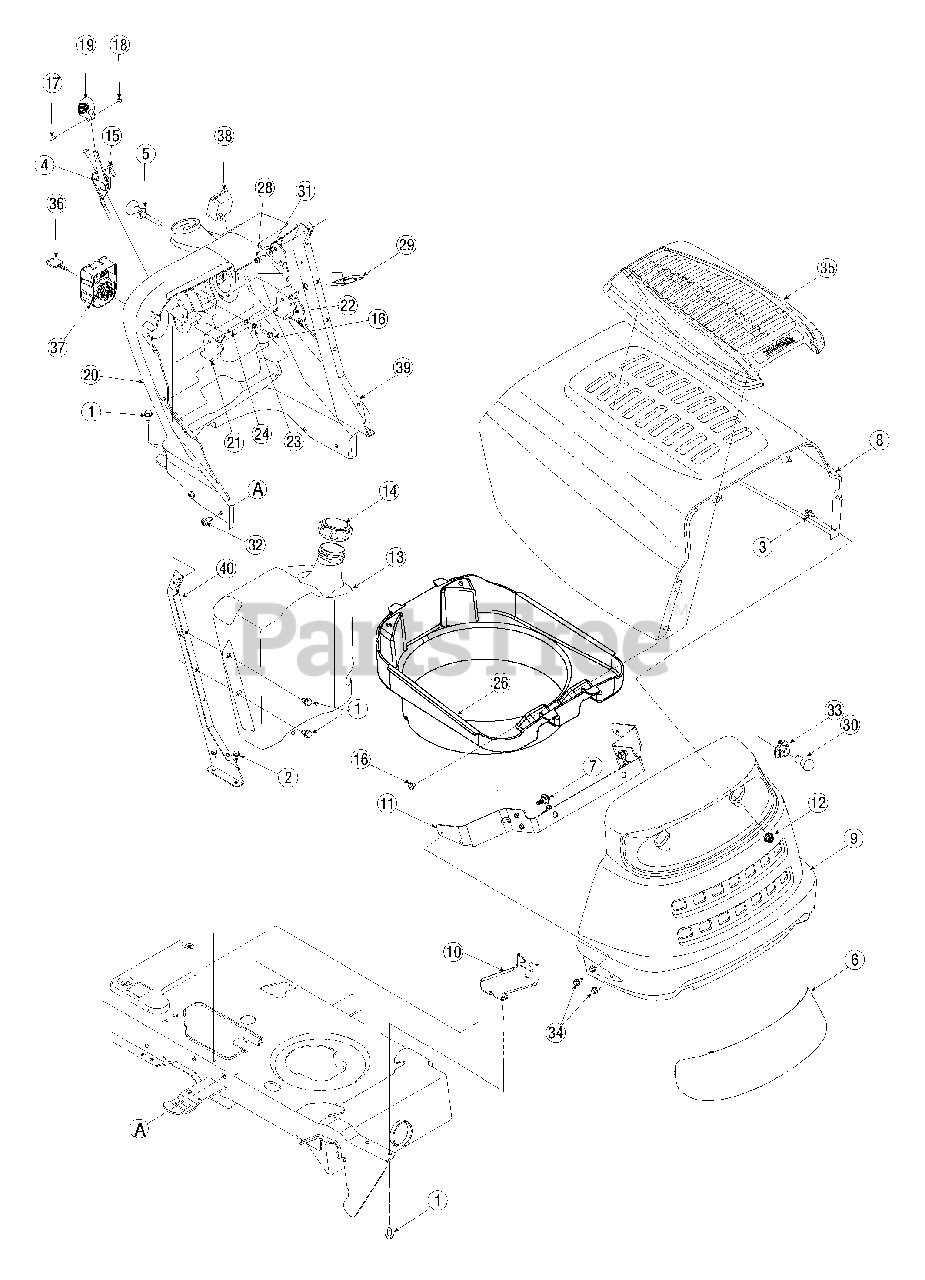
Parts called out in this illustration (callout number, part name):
1	Screw, 5/16-12 x.750
2	Self-tapping Screw, 1/4-20 x.5
3	Hex Cap Screw, 1/4-20 x.62
4	Throttle Cable
5	Choke Knob/Cable
6	Headlight Lens
7	Shoulder Screw,.43 x.29
13	Fuel Tank, Three Gallon
14	Fuel Cap
15	Screw, 1/4-14 x.625
16	Self-tapping Screw, 1/4-15 x.75
17	Truss Phillips Screw, #8-32 x.375
18	Hex Nut, #8-32
19	Throttle Control Knob
20	Dash Panel
21	Cruise Control Button
22	Parking Brake Button
23	Flat Washer, 9/32 x 1/2 x 1/16
24	Brake/Cruise Pivot Rod
26	Hood Plenum
28	Self-tapping Screw, 1/4-20 x.75
29	Switch Brkt., Electric PTO
30	Lamp
31	Bell Washer,.265 x.75 x.062
32	Screw, 5/16-18 x.75
33	Headlight Socket
34	Hex Index Screw, 1/4-20 x.625
35	Hood Cover, 5 Style
36	Ignition Key w/ plastic cover
37	Ignition Switch
38	Systems Ind. Monitor w/ Hour Meter
